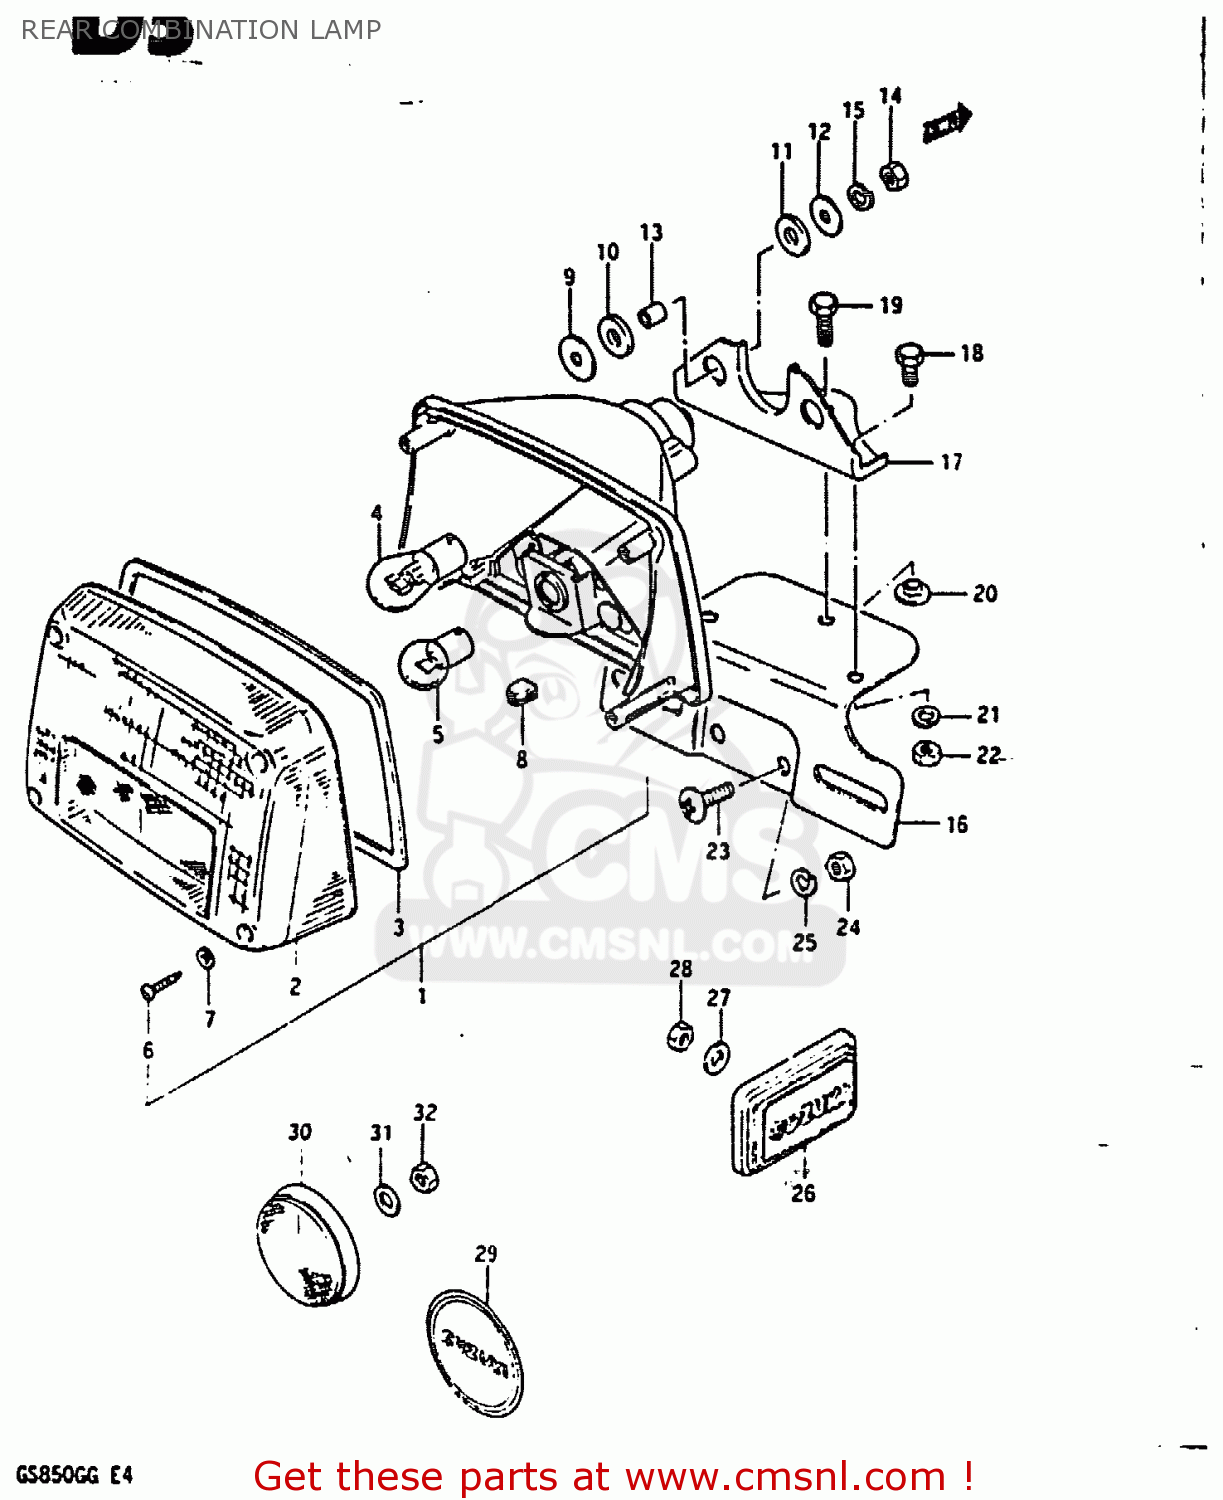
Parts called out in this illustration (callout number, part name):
1	LAMP ASSY, REAR COMBINATION
2	LENS
3	GASKET (NAS)
4	BULB(12V23W)
5	BULB
6	SCREW,REAR COMBINATION LAMP
7	GASKET (NAS)
8	GROMMET
9	WASHER
10	CUSHION
11	CUSHION
12	WASHER(6,5X22X1.6)
13	SPACER(6.1X9X7.5)
14	NUT
15	WASHER,LOCK
16	BRACKET, LICENCE PLATE
17	BRACKET,REAR COMBINATION LAMP
18	BOLT
19	BOLT
20	WASHER
21	WASHER,LOCK
22	NUT
23	SCREW
24	NUT
25	WASHER,LOCK
26	EMBLEM, REAR SIDE
27	WASHER
28	NUT
29	EMBLEM, REAR
30	REFLEX REFLECTOR,RR
31	WASHER
32	NUT
